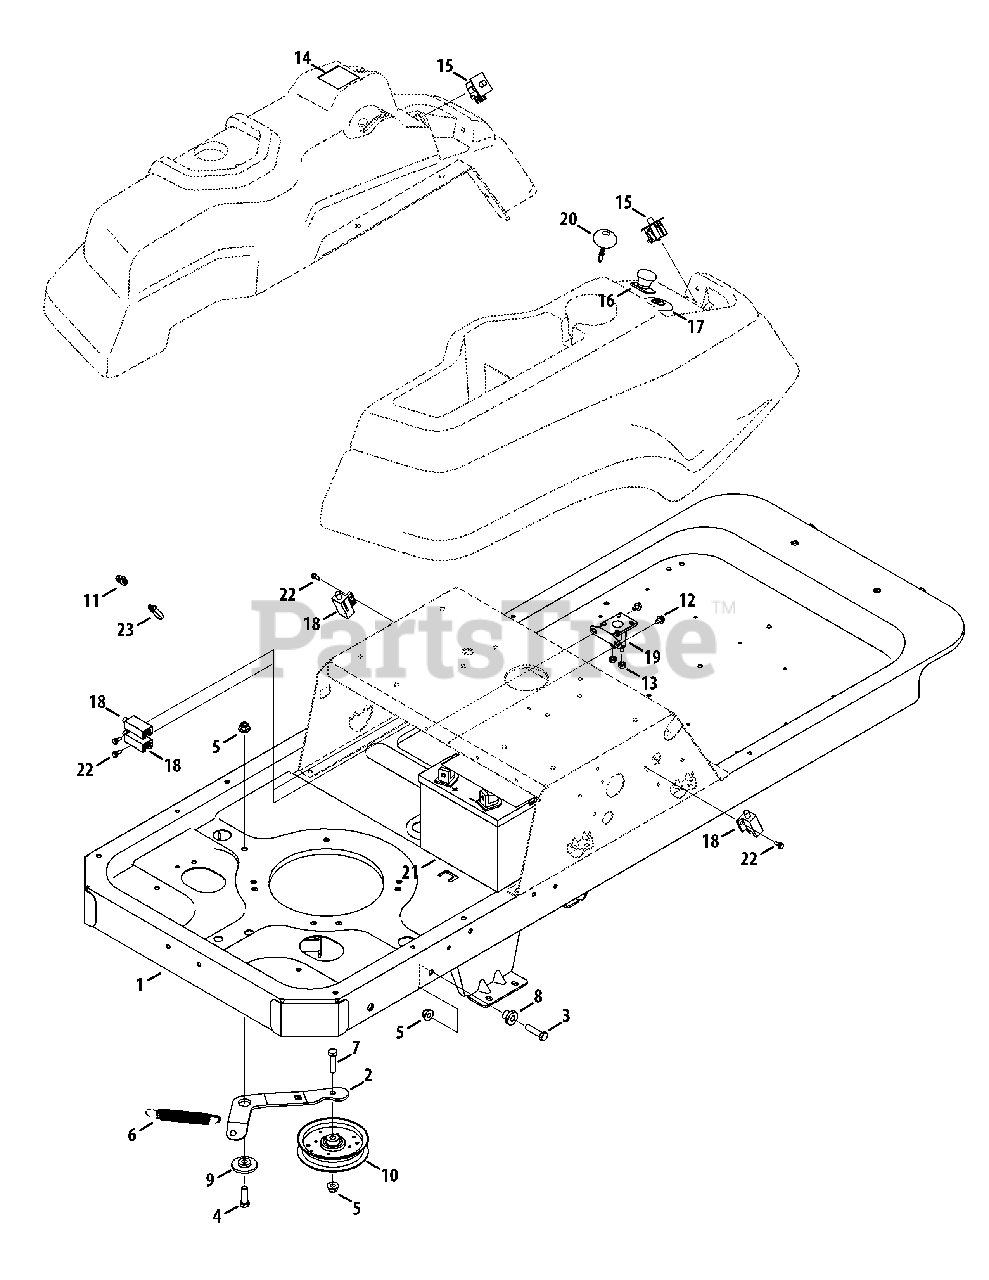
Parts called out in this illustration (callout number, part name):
1	Frame Assembly
3	Hex Screw, 3/8-16 x 1.5
4	Hex Screw, 3/8-16 x 1.25
5	Flange Nut, 3/8-16
6	Extension Spring, .75 x 5.06
7	Hex Screw, 3/8-16 x 1.5
8	Shoulder Spacer, .39 x 1.0 x .7
9	Shoulder Spacer, .884 x .19
10	Idler Pulley, 4.25 Dia.
11	Wire Harness
12	Hex Screw, 1/4-20 x .375
13	Hex Nut, 1/4-20
14	Hour Meter
15	Neutral Switch
16	PTO Switch
17	Ignition Switch
18	Interlock Switch
19	Solenoid
20	Key
21	Battery
22	Shoulder Screw, #10-32 x .500
23	Cable Tie
